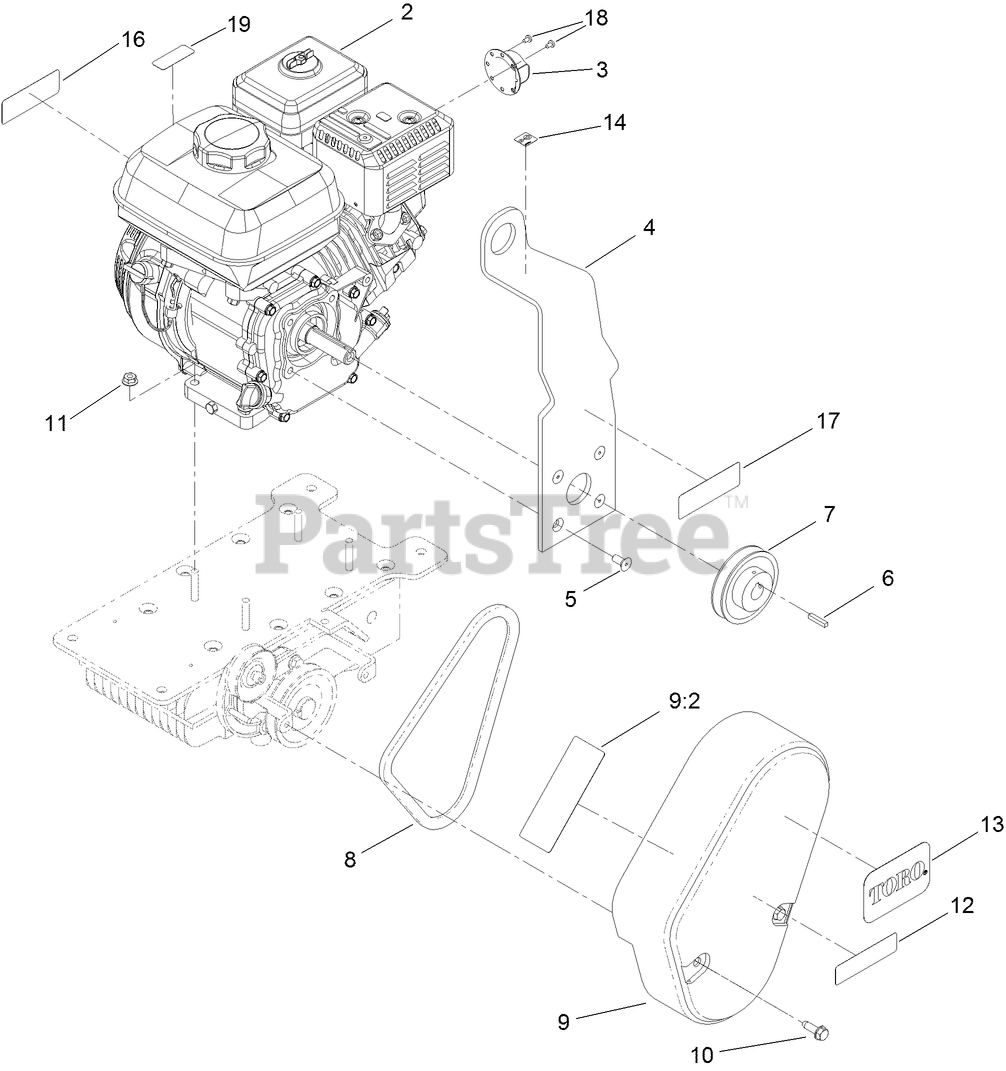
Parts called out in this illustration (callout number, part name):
2	ENGINE-HONDA, GX160
3	DEFLECTOR
4	PLATE-EYE, LIFT
5	SCREW
6	KEY-SQUARE
7	SHEAVE
8	BELT-V
9	BELT GUARD ASM
9:2	DECAL-WARNING
10	SCREW-THD ROLL, HWH
11	NUT-FLANGE
14	DECAL-POINT, LIFT
16	DECAL-ARRESTER, SPARK
17	DECAL-WARNING
18	SCREW-SELF TAPPING
19	DECAL-WARNING, ETHANOL
